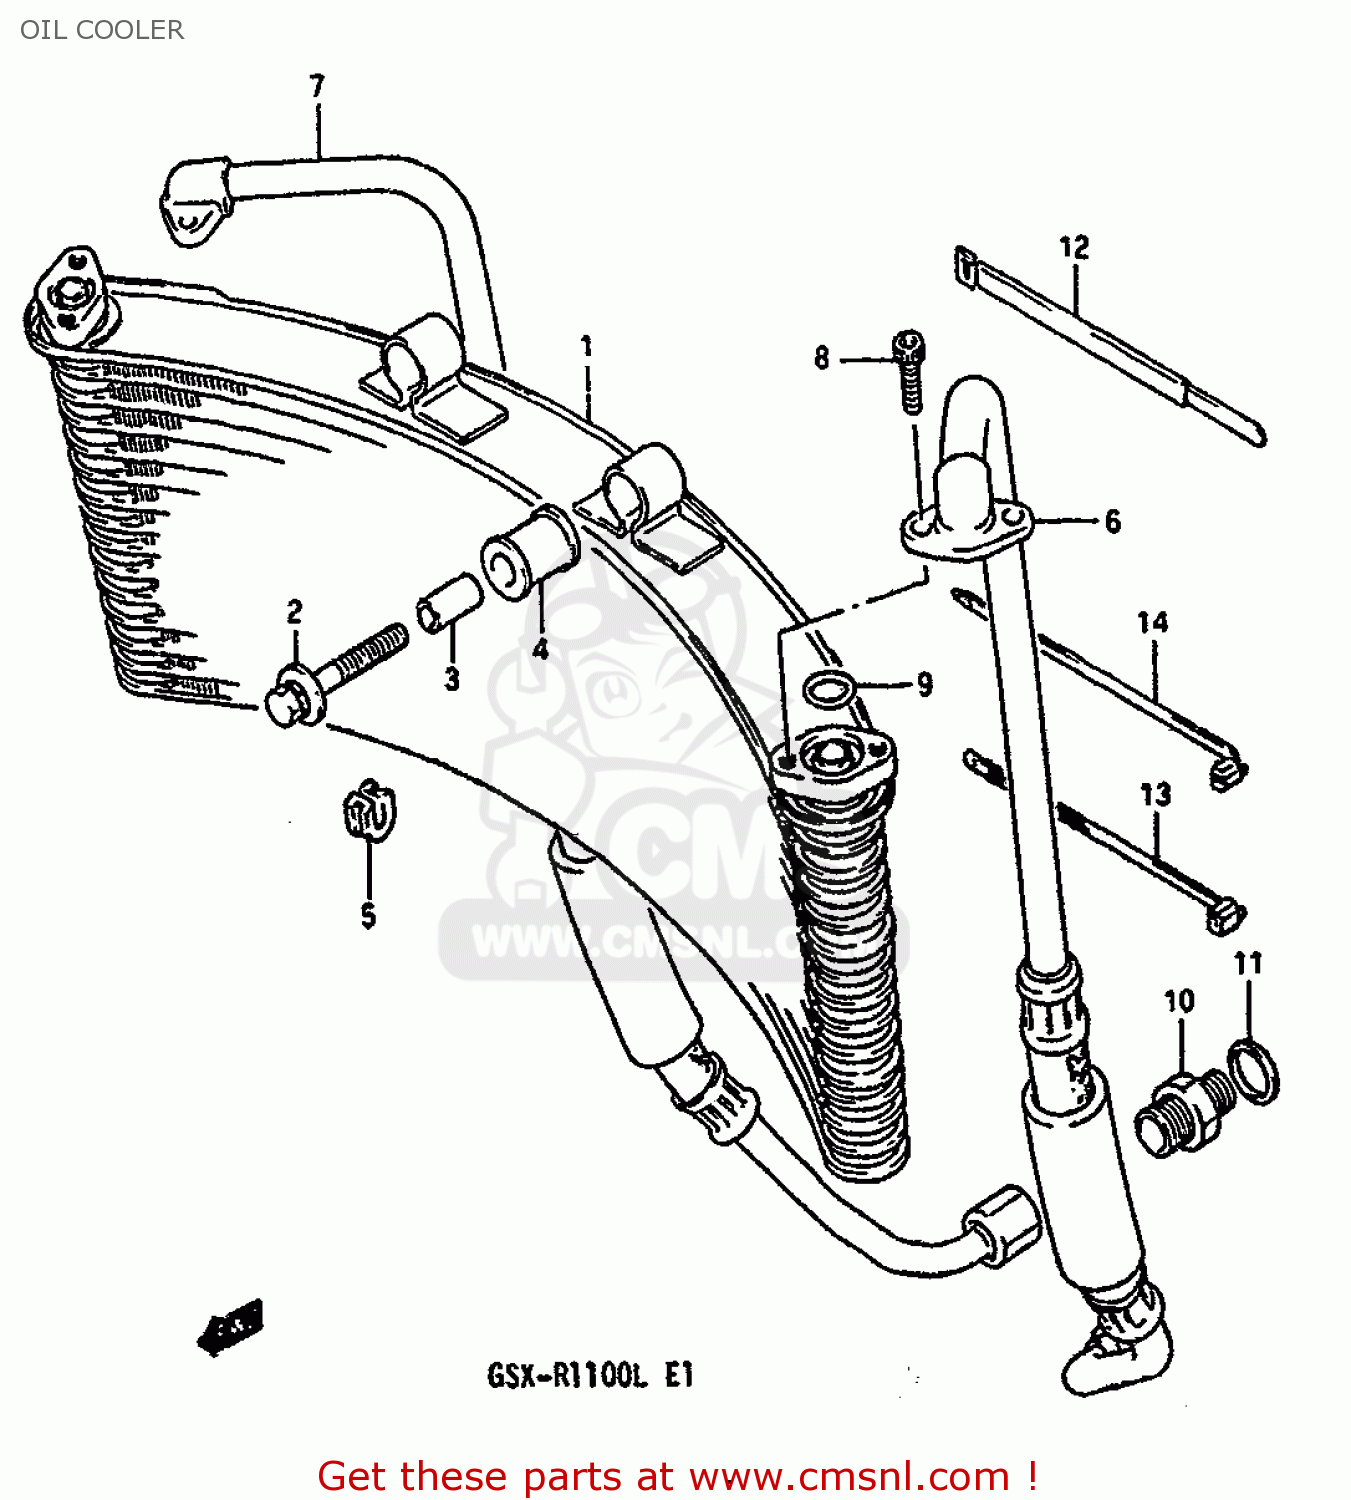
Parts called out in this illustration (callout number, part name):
1	COOLER ASSY,OIL
2	BOLT(8X40)
3	SPACER (8.8X12X24.5)
4	CUSHION,OIL COOLER NO.1
5	CUSHION,OIL COOLER NO.2
6	HOSE,OIL
7	HOSE,OIL
8	BOLT
9	O RING(D:2.4,ID:12.3)
10	BOLT UNION
11	GASKET(16X22X2) (NAS)
12	CLAMP(L:250)
13	CLAMP
14	CLAMP(L:235)
